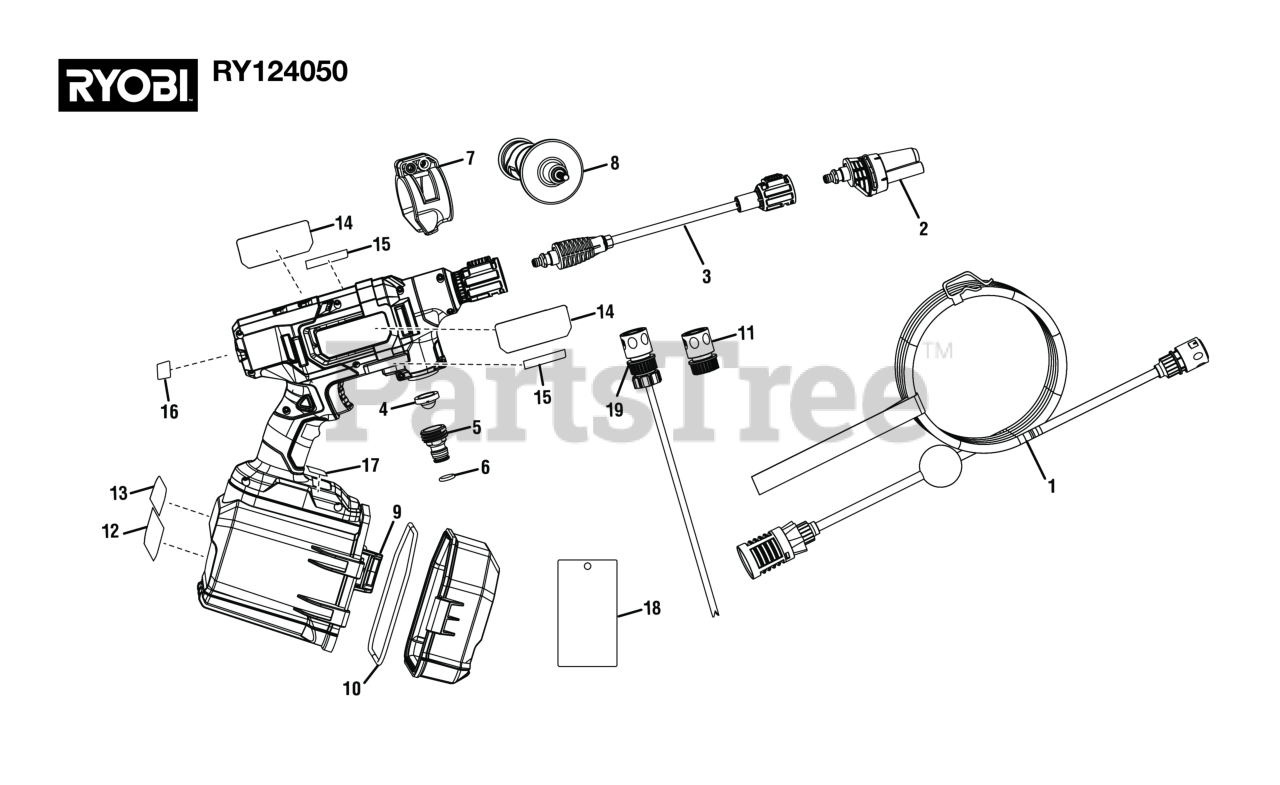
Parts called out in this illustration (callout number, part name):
1	Suction Hose with Swivel Connector
2	3-in-1 Nozzle
3	Extension Pole
4	Water Inlet Filter
5	Inlet Connector
6	O-Ring (ID11.3 x CS2.5)
7	Handle Grip Mount
10	O-Ring Seal (ID142.5 x CS4)
11	Quick-Connect Adaptor
12	Icon/Danger Label
13	Data Label
14	RYOBI HP Logo Label
15	EZCLEAN Logo Label
16	LED Mode Label
17	BRUSHLESS Logo Label
18	Danger Hangtag
19	1- to 2-Liter Bottle Connector
